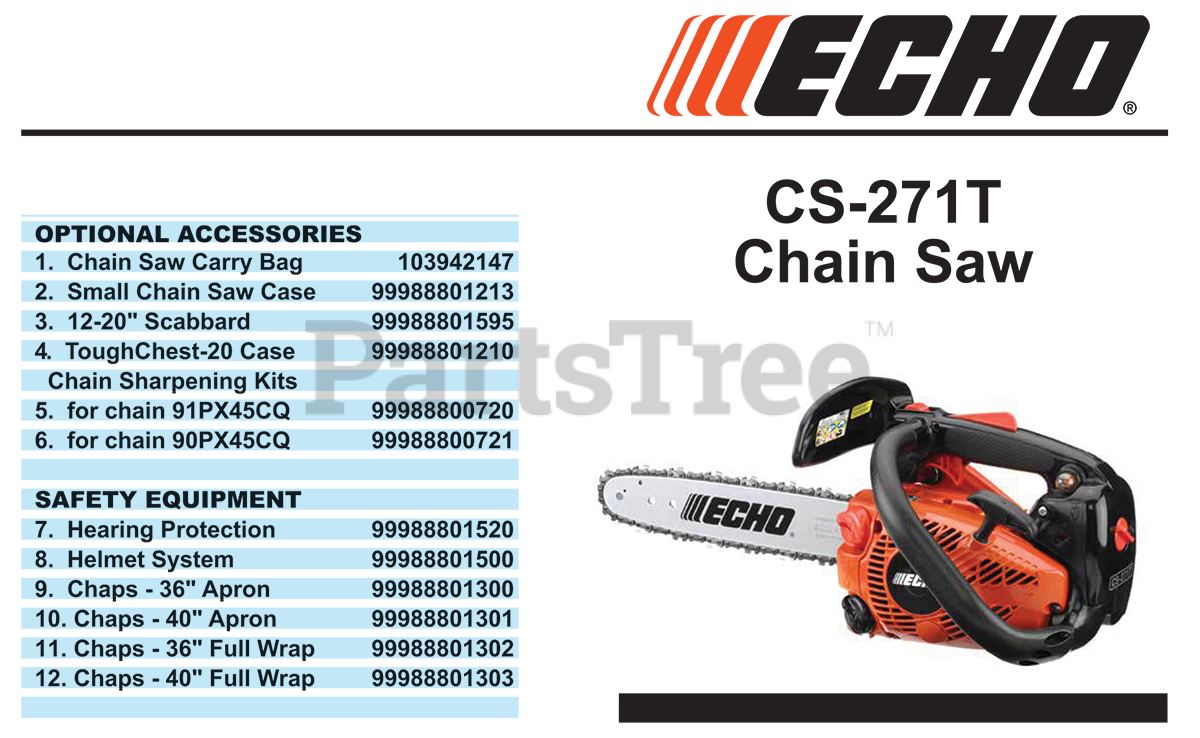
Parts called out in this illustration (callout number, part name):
1	Chain Saw Carry Bag
2	Small Chain Saw Case
3	12-20" Scabbard
4	ToughChest-20 Case
5	Sharpener for chain 91PX45CQ
6	Sharpener for chain 90PX45CQ
7	Hearing Protection
8	Helmet System
9	Chaps - 36" Apron
10	Chaps - 40" Apron
11	Chaps - 36" Full Wrap
12	Chaps - 40" Full Wrap
